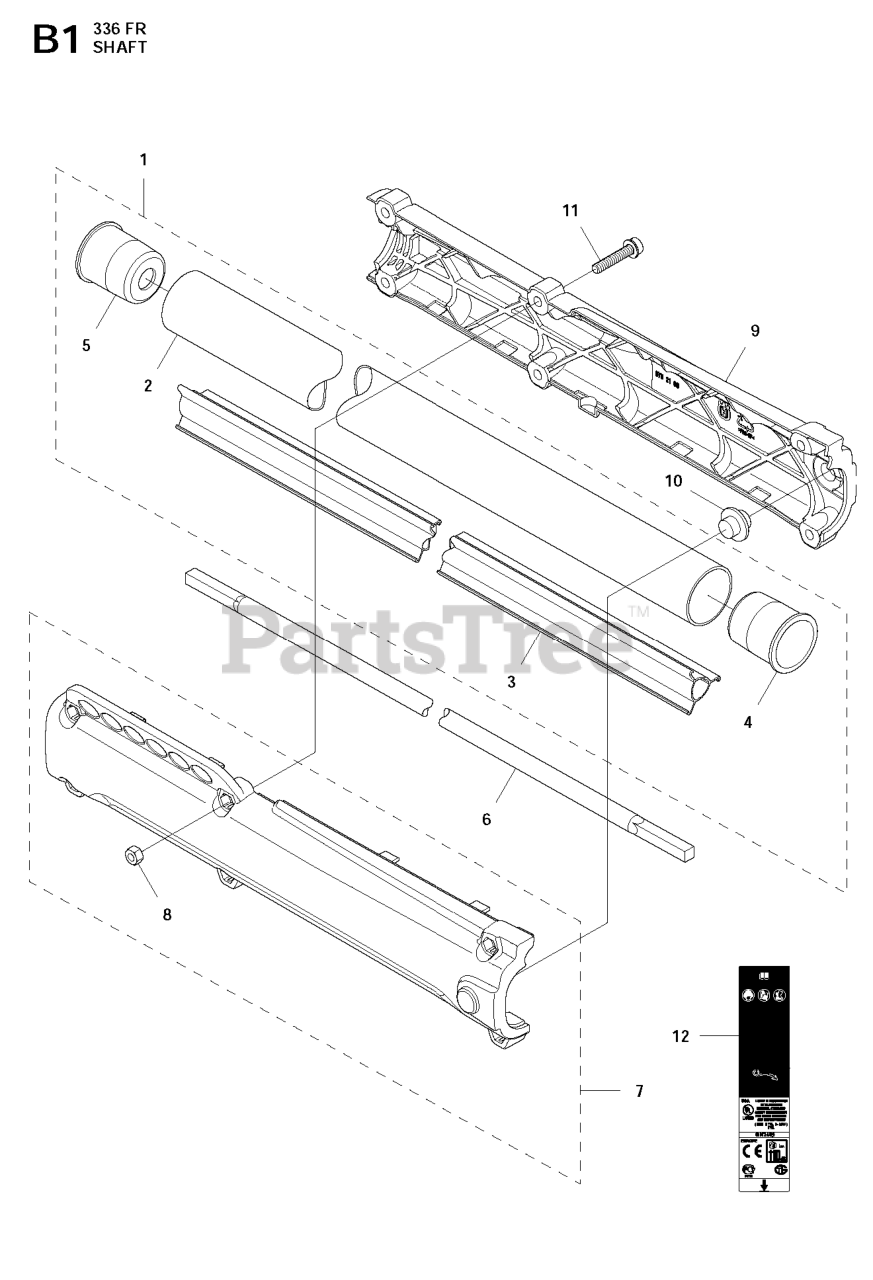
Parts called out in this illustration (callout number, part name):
2	TUBE
5	PLUG
7	WEAR PROTECTION
8	SCREW M6S 5X20
9	WEAR PROTECTION
10	VIBRATION ABSORBER
12	LABEL WARNING TRIMMERS AND BRU
